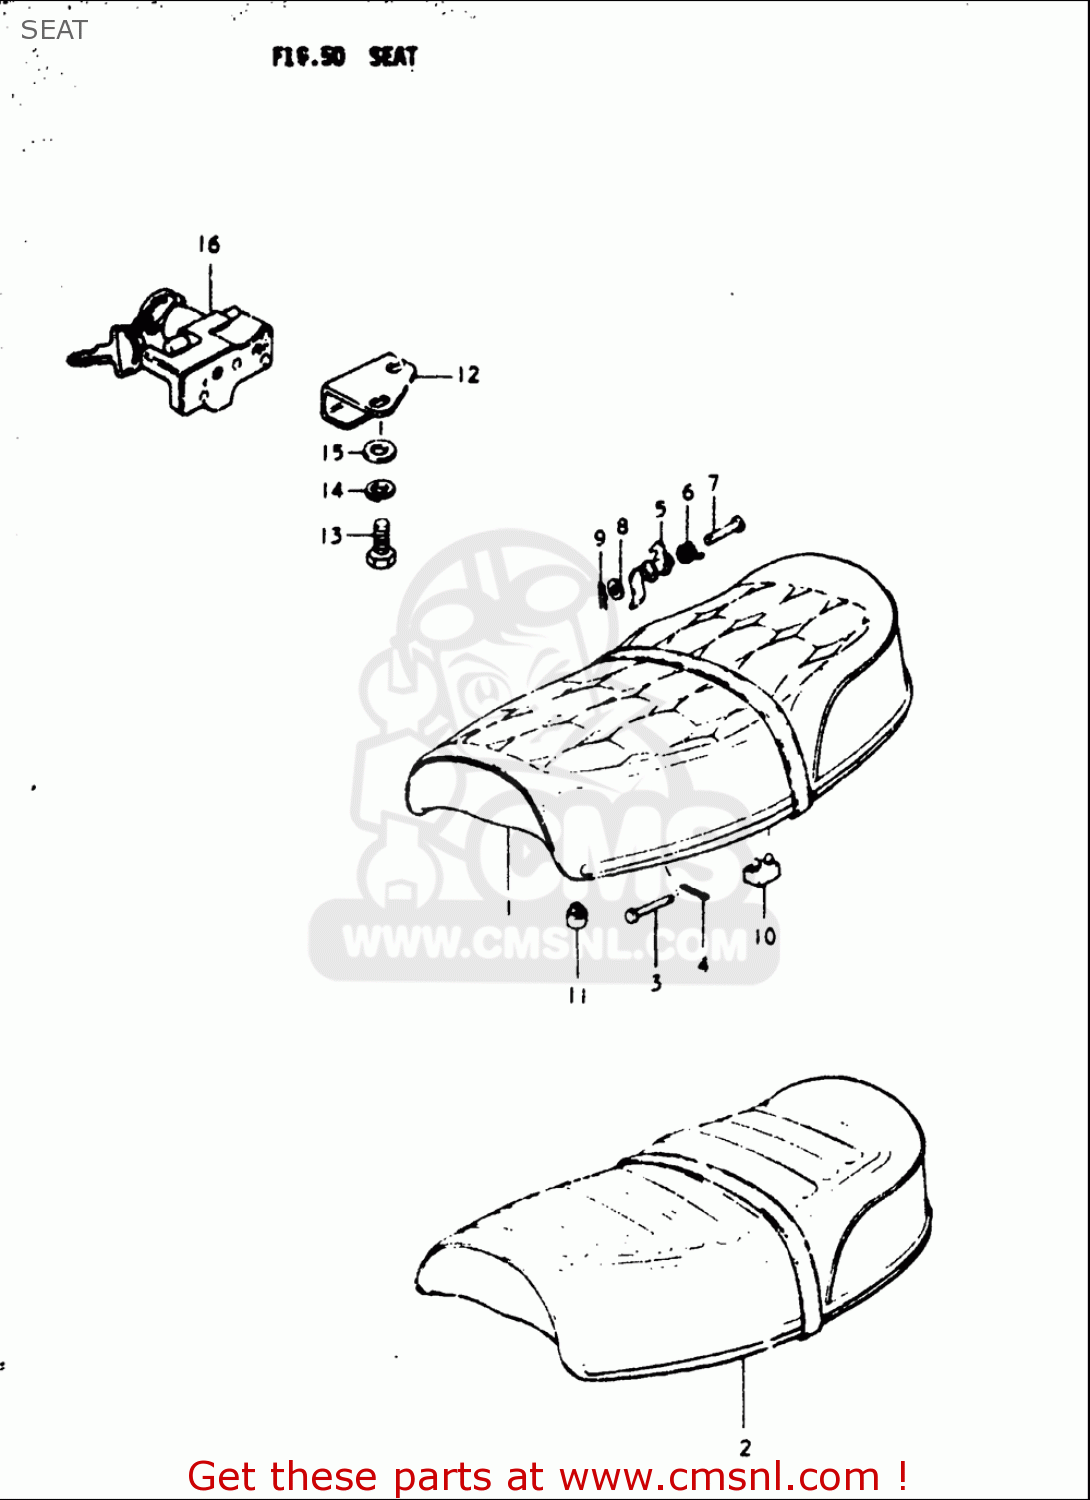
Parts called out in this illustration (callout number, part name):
1	SEAT ASSY
2	SEAT ASSY
3	PIN
4	PIN
6	SPRING
7	PIN
8	WASHER
10	CUSHION
11	CUSHION
12	PLATE,SEAT CLAMP GUIDE
13	BOLT
14	WASHER,LOCK
15	WASHER
16	LOCK SET,HELMET
